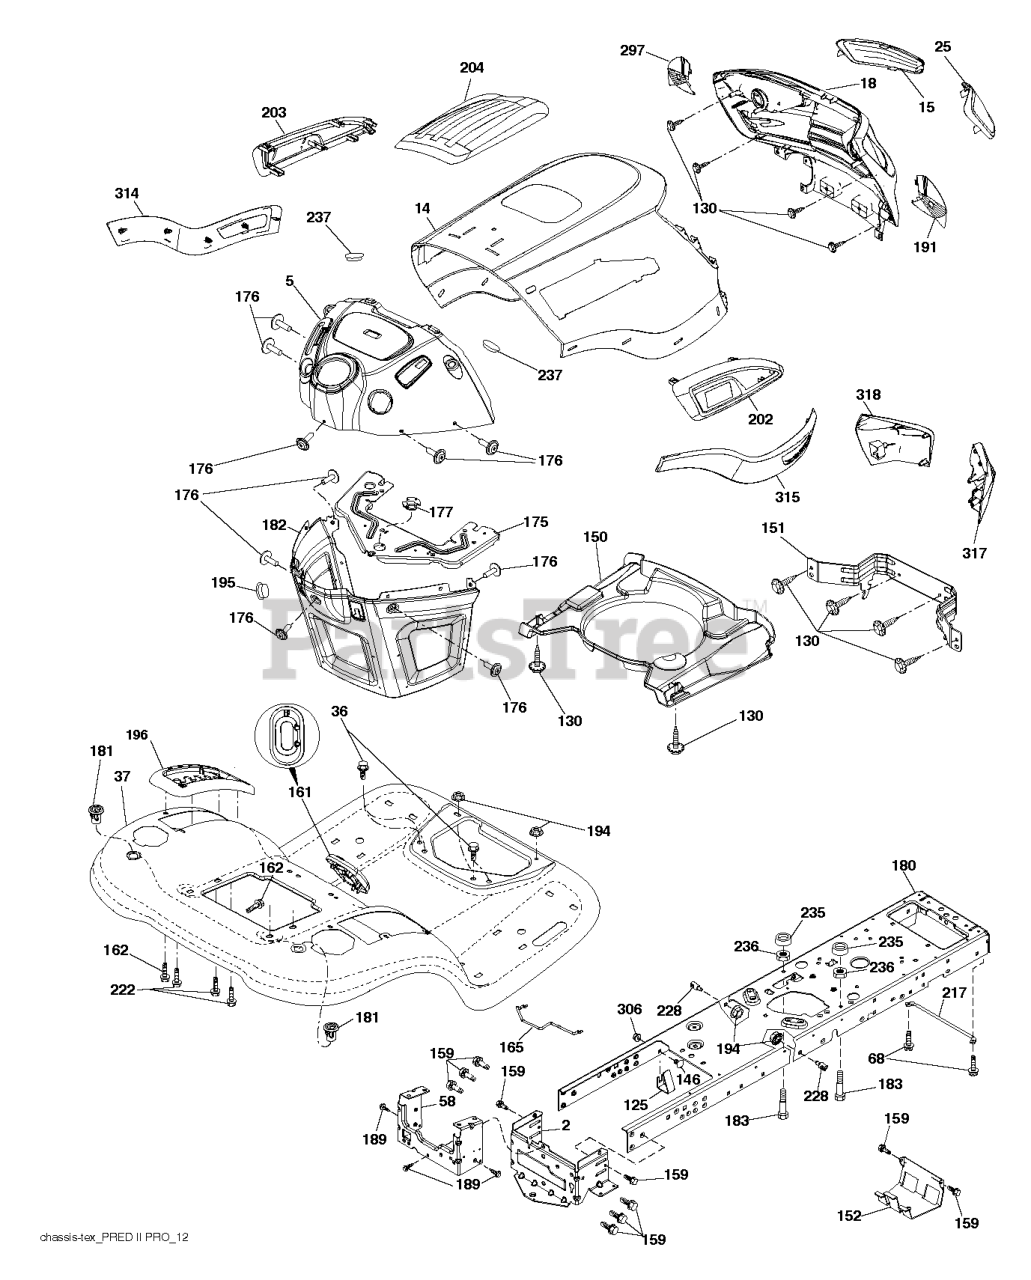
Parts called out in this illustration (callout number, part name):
2	DRAWBAR.LOWER.2PC.18/22
3	APPLIQUE.SUBASM.GT.HUSQ.II
5	DASH.YT.PRED.SQG.EL.W/C.BLK
14	HOOD HOOD.GRILL.PREDII.YT/GT.Y
15	LENS.LH.PRED II.YT.CLR.SVC
18	GRILLE.PRED2.GT.PRO.REDMAX
25	LENS.RH.PRED II.YT.CLR.SVC
36	SCREW 5/16"
37	FENDER FENDER PNT CONVERSION 4
58	DRAWBAR.UPPER.2PC,LRG.FENDER
68	SCREW LT
125	CLIP.FUEL.LINE
130	SCREW.#10 X 0.750.BOS
146	BOLT.RDHD.SHT.SQNK.3/8-16X5/8
150	PREDATOR.YT.GT.HOOD.AIR DUCT
151	BRACKET.PIVOT.PREDATOR
152	SHIELD.BROWNING/DEBRIS
159	SCREW, 3/8-16X3/4
161	CONSOLE.FUEL.WINDOW.STGT.BLACK
162	SCREW.HI-LO.CONSOLE
165	SUPPORT.TANK.REAR.B/TE
175	PLATE.CROSSMEMBER.HUSQ
176	SCREW.#10-24X5/8.RN.QU
177	BUSHING STEERING
180	CHASSIS.TEX.BOLTED
181	BUSHING.MNT.FEND.CRGO.
182	DASH.LOWER.COMMON.12V.ADAPTOR
183	BOLT.5/16-18X1-1/4 FULL THD
189	SCREW
191	INSERT INSERT.REFLECTIVE.RH
194	NUT LOCK HEX FLANGE 5/16-18
195	PLUG.HOLE.DASH.LOWER.12V.BLK
196	CONSOLE ASM DECK LIFT BLACK
202	VENT SIDE. HOOD. PREDATOR II.
203	VENT SIDE. HOOD. PREDATOR II.
204	VENT ASM.TOP.PRED GT PRO.428
217	ROD.PIVOT.HOOD
222	SCREW.1/4-20X5/8
228	STUD.FASTNER.W/ANTI-ROTATE
235	SPACER FENDER
236	NUT.CENTERLOCK.5/16-
237	PLUG.MOUNT.CARGO.BLK
297	INSERT INSERT.REFLECTIVE.LH
306	NUT LOCK FLG 3/8-16 UNC
314	TRIM SUBASM. PREDATOR II. YT/G
315	TRIM SUBASM. PREDATOR II. YT/G
317	BUMPER CORNER. PREDATOR II. GT
318	BUMPER CORNER. PREDATOR II. GT
